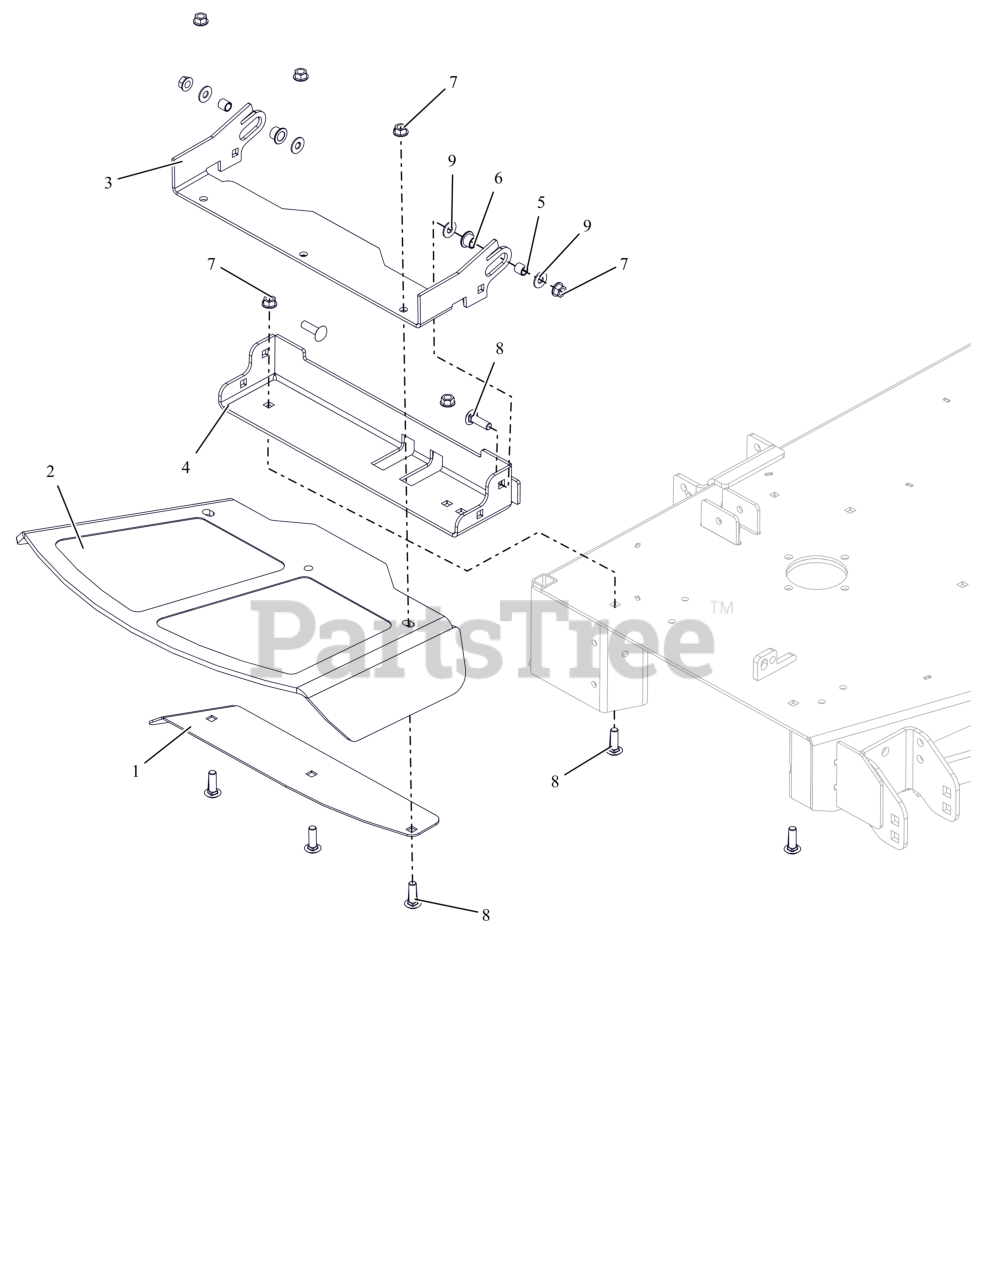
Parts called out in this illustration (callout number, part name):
1	48-60 DISCH CHUTE CLMP PLT-RED
2	CHUTE, FORMED RUBBER DISCHARGE
3	BRKT, CHUTE MOUNT (RED)
4	BASE, DISCHARGE CHUTE MTG BRKT (RED)
5	SPCR, .385X.500X.350
6	BSHG, FLANGED .50X.625X.50X.062
7	NUT-LK-CTR-FLG .375-16 GF ZCC
8	BLT,RHSSN .38-16X1.25 G5 ZCC
9	WSHR, HDND 0.375X0.875X0.064 ZCC
